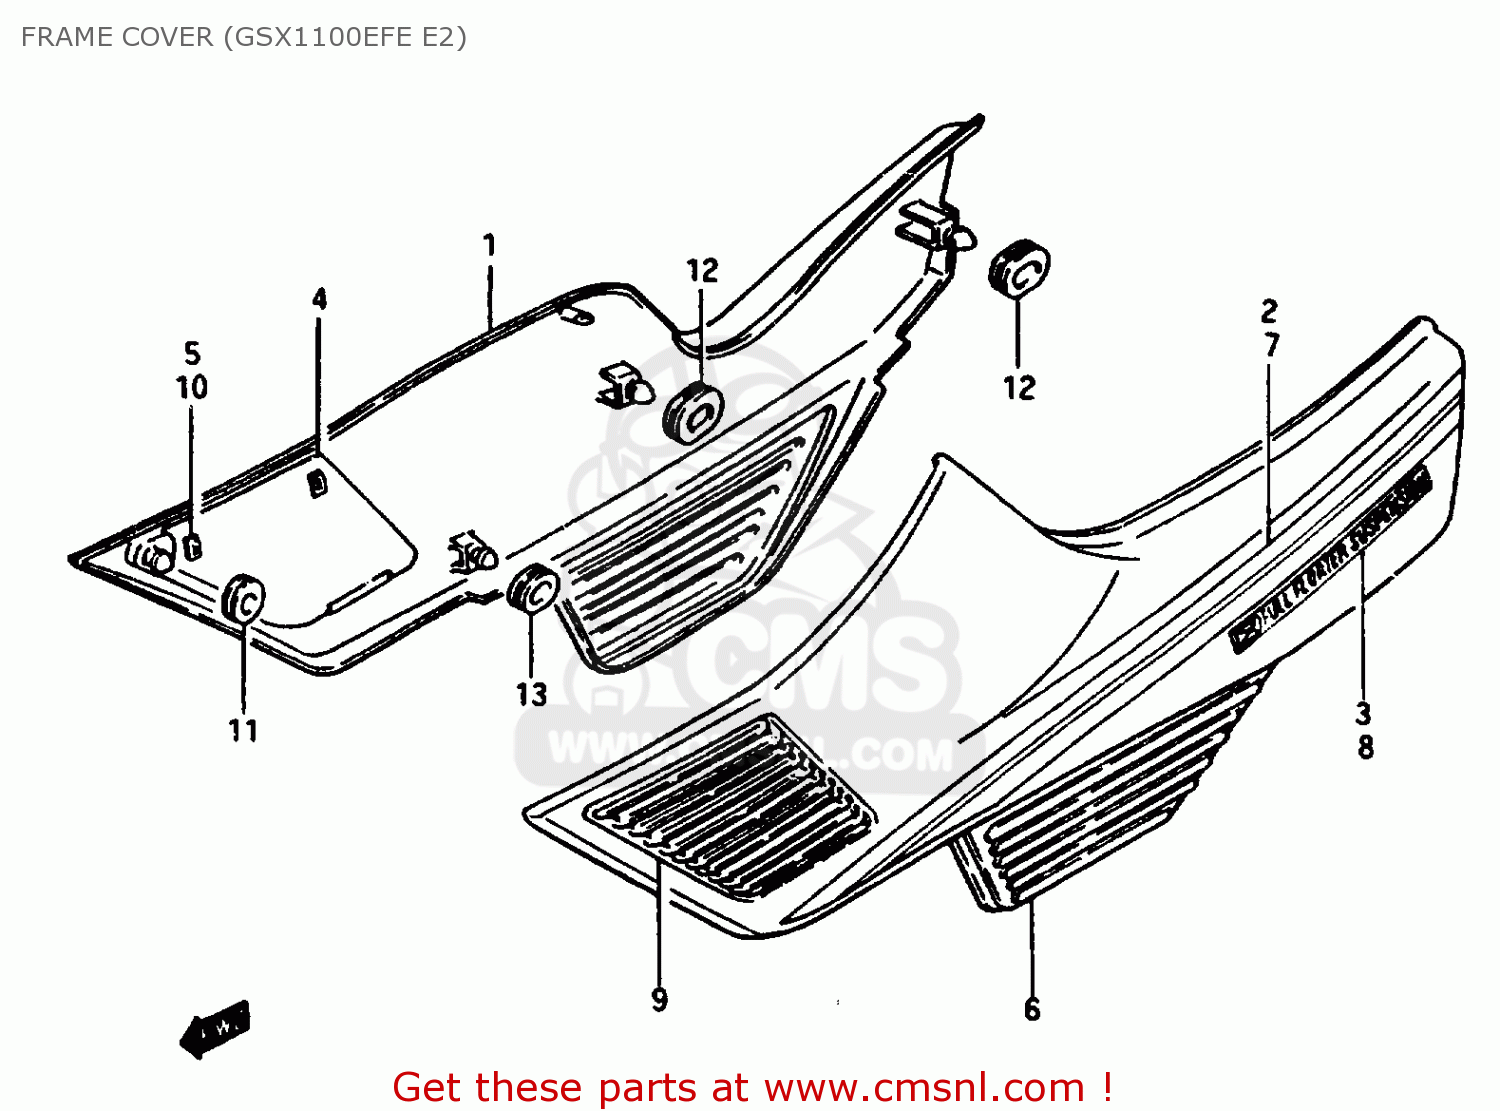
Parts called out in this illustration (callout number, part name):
1	COVER, FRAME RH
2	TAPE SET, RH (WHITE)
3	EMBLEM
4	COVER,FRAME,RIGHT
5	NUT
6	COVER, FRAME LH
7	TAPE SET, LH (WHITE)
8	EMBLEM
9	COVER,FRAME,RIGHT NO.1
10	NUT
11	CUSHION
12	CUSHION
13	CUSHION
